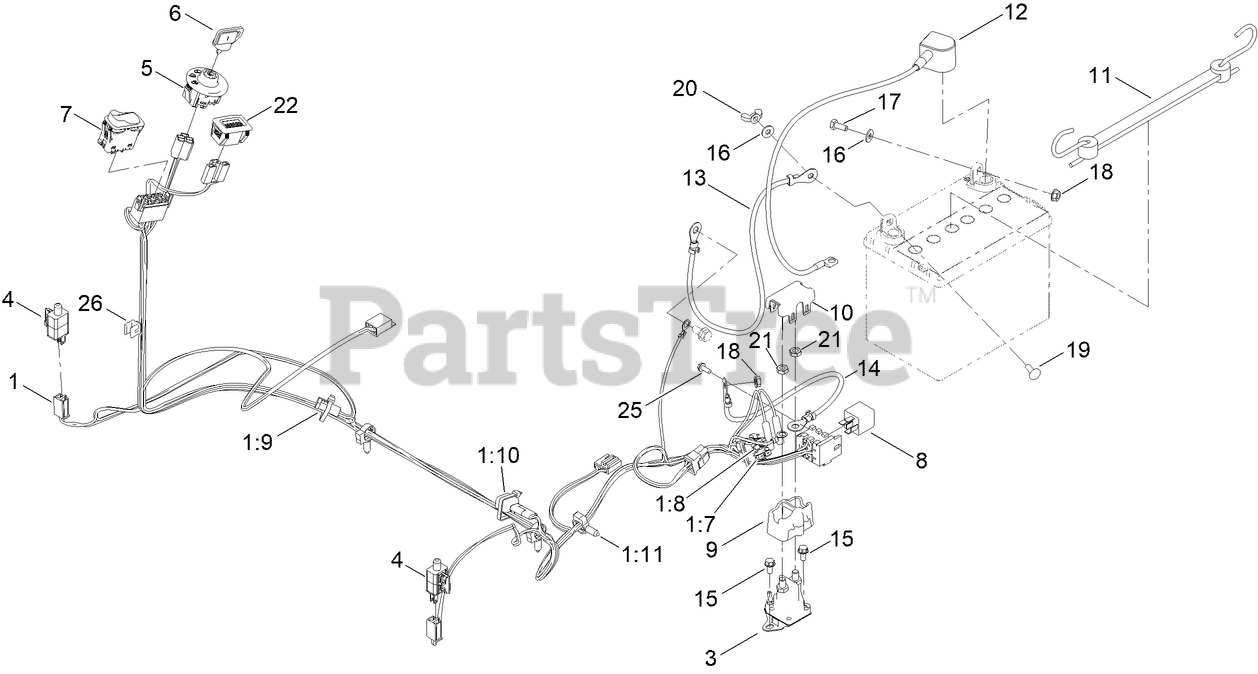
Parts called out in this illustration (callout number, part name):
1	HARNESS-WIRE, MAIN
1:7	FUSE-BLADE, 15 AMP
1:8	FUSE-BLADE, 25 AMP
1:9	CAP-OVER MOLD, 1M/1F
1:11	CLIP-TUBING, HARNESS
3	SOLENOID
4	SWITCH
5	SWITCH-IGNITION
6	KEY-IGNITION
7	SWITCH-ROCKER, ON-NONE-ON
9	COVER-SOLENOID
10	CAP-SOLENOID
11	HOLDDOWN-BATTERY
12	CABLE-BATTERY,RED
13	CABLE-BATTERY, BLACK
14	CABLE-BATTERY, POSITIVE
15	SCREW-HWH
16	WASHER
17	SCREW-HH
18	NUT-HF
19	BOLT-CARR
20	NUT-WING
21	NUT-HJ
22	HOUR METER
25	SCREW-TAPTITE
26	CLIP-EDGE W/TIE, PERPENDICULAR
